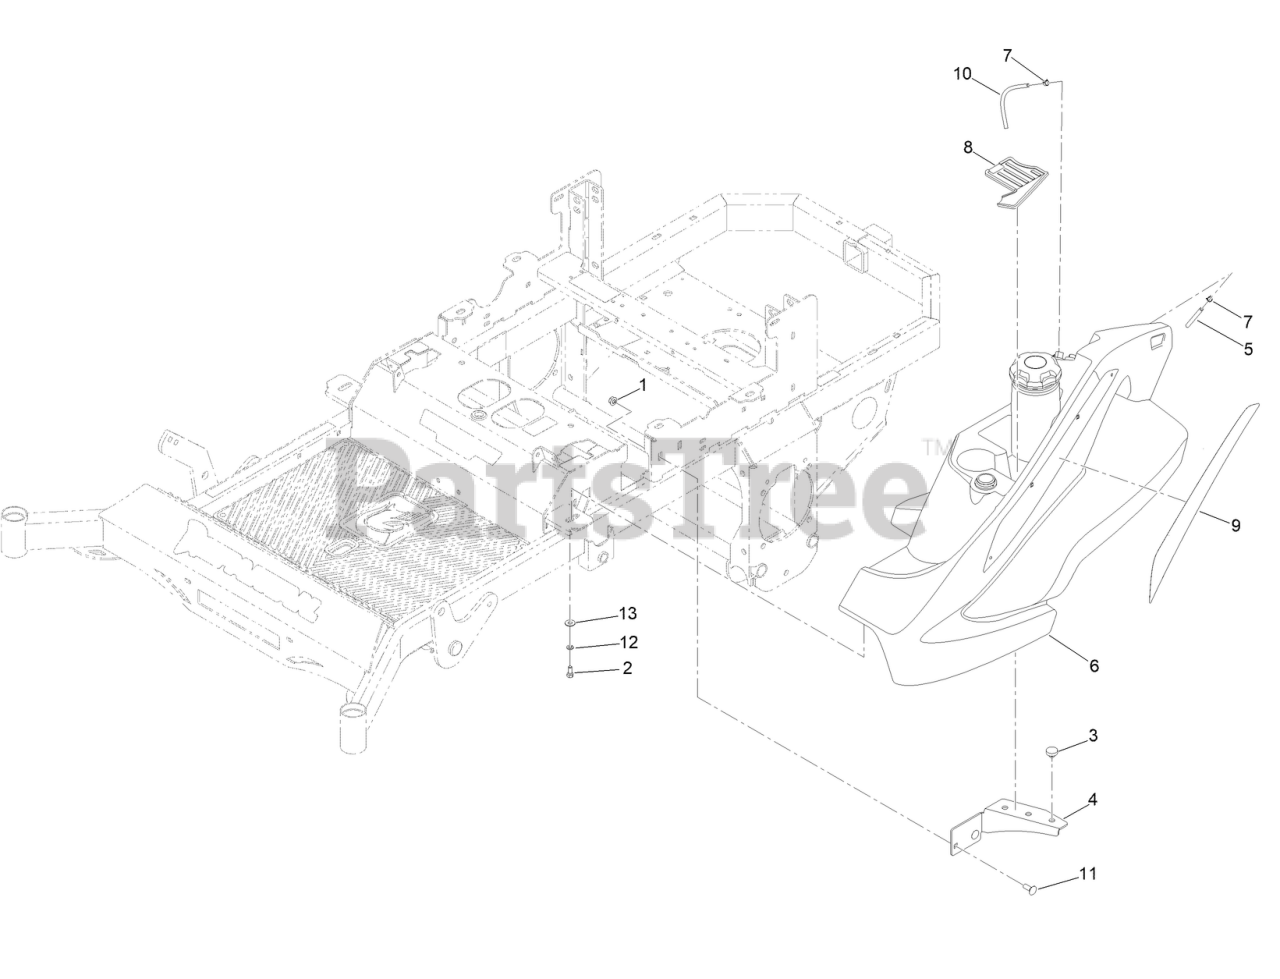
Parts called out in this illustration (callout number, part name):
1	3/8-16 HEX FLANGE NUT W/SERR ZINC YELLOW
2	SCREW-HH
3	PUSH-IN RUBBER BUMPER MWR FLOOR
4	RT/SRT GAS TANK SUPPORT PAINTED
5	MWR FUEL TANK BLACK 3/16IN VENT TUBE 1FT
6	MWR GASOLINE FUEL TANK ASSY
7	1/2IN (#8) HOSE CLAMP
8	RUBBER TANK STORAGE COMPARTMENT INSERT
9	DECAL-TANK
10	1/4IN SAE J30R7 BULK HOSE 1FT
11	3/8-16 X 1 CARRIAGE BOLT YZ GR.8
12	WASHER-LOCK
13	WASHER-FLAT
